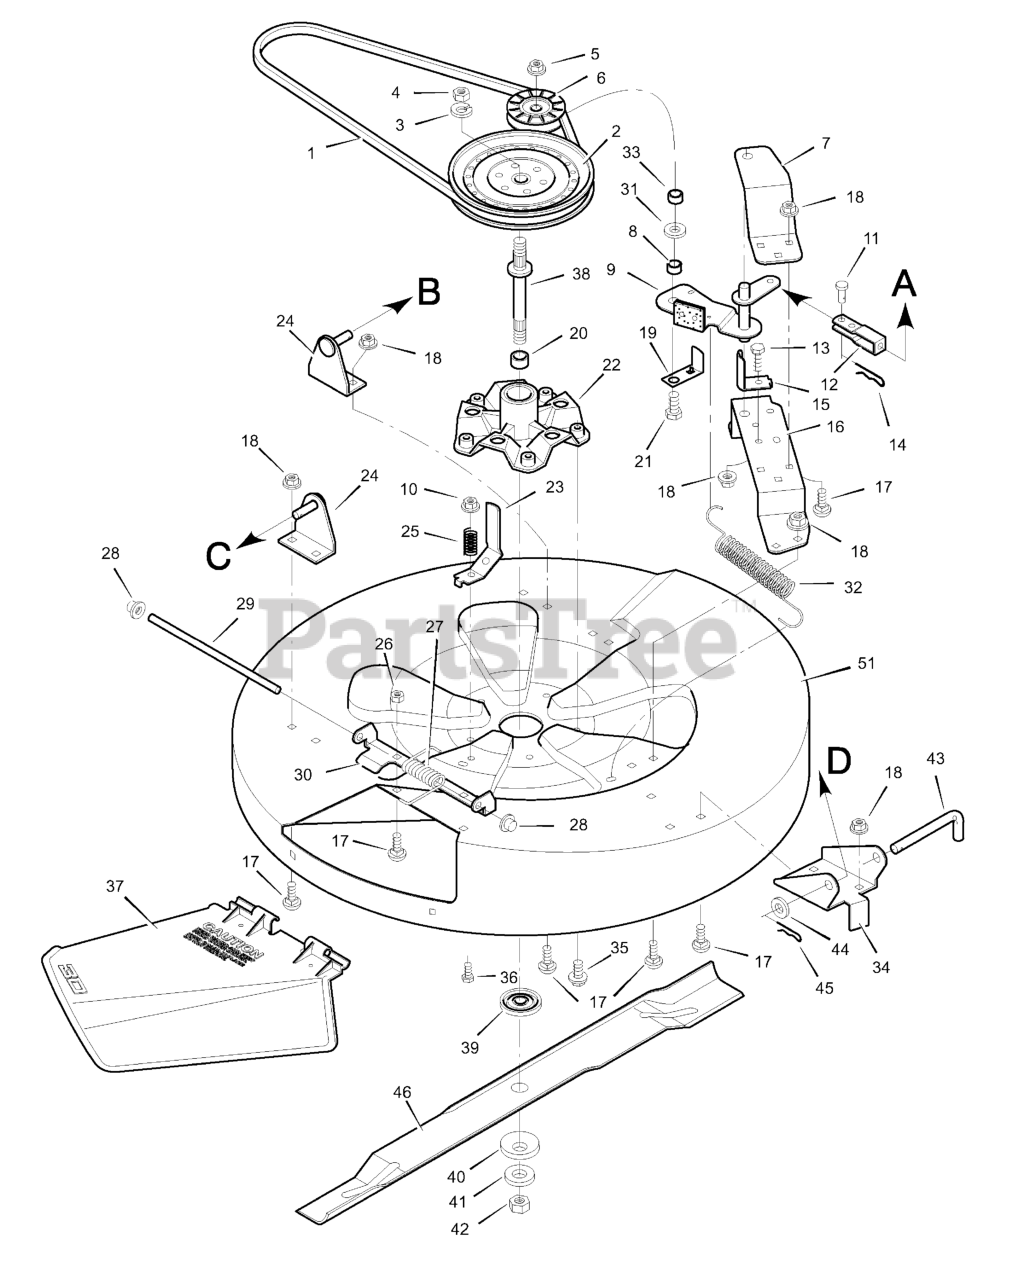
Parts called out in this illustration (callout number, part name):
1	Belt, Mower Drive
2	Pulley, Splined
3	Lockwasher
4	Locknut, Hex
5	Nut, Hex
6	Pulley, Idler
7	Bracket, Upper Idler
9	Assembly, Blade Idler
10	Locknut, Flange
11	Pin, Clevis
13	Bolt, Hex
14	Pin, Hair
15	Guide, Belt
16	Bracket, Lower Idler
17	Bolt, Carriage
18	Nut, Flange
19	Guide, Belt
21	Bolt, Hex
22	Housing, Mandrel
23	Guide, Belt
24	Bracket, Hanger
25	Spring, Compression
26	Nut, Hex
27	Spring - Torsional
28	Push On Cap
30	Hinge, Chute Deflector
32	Spring, Extension
34	Bracket, Front
36	Bolt, Hex
37	Deflector, Chute
38	Mandrel
39	Adapter, Blade
40	Washer, Belleville
41	Washer, Hardened
42	Nut, Hex
43	Pin, Pull
45	Pin, Hair
46	Blade, Standard
